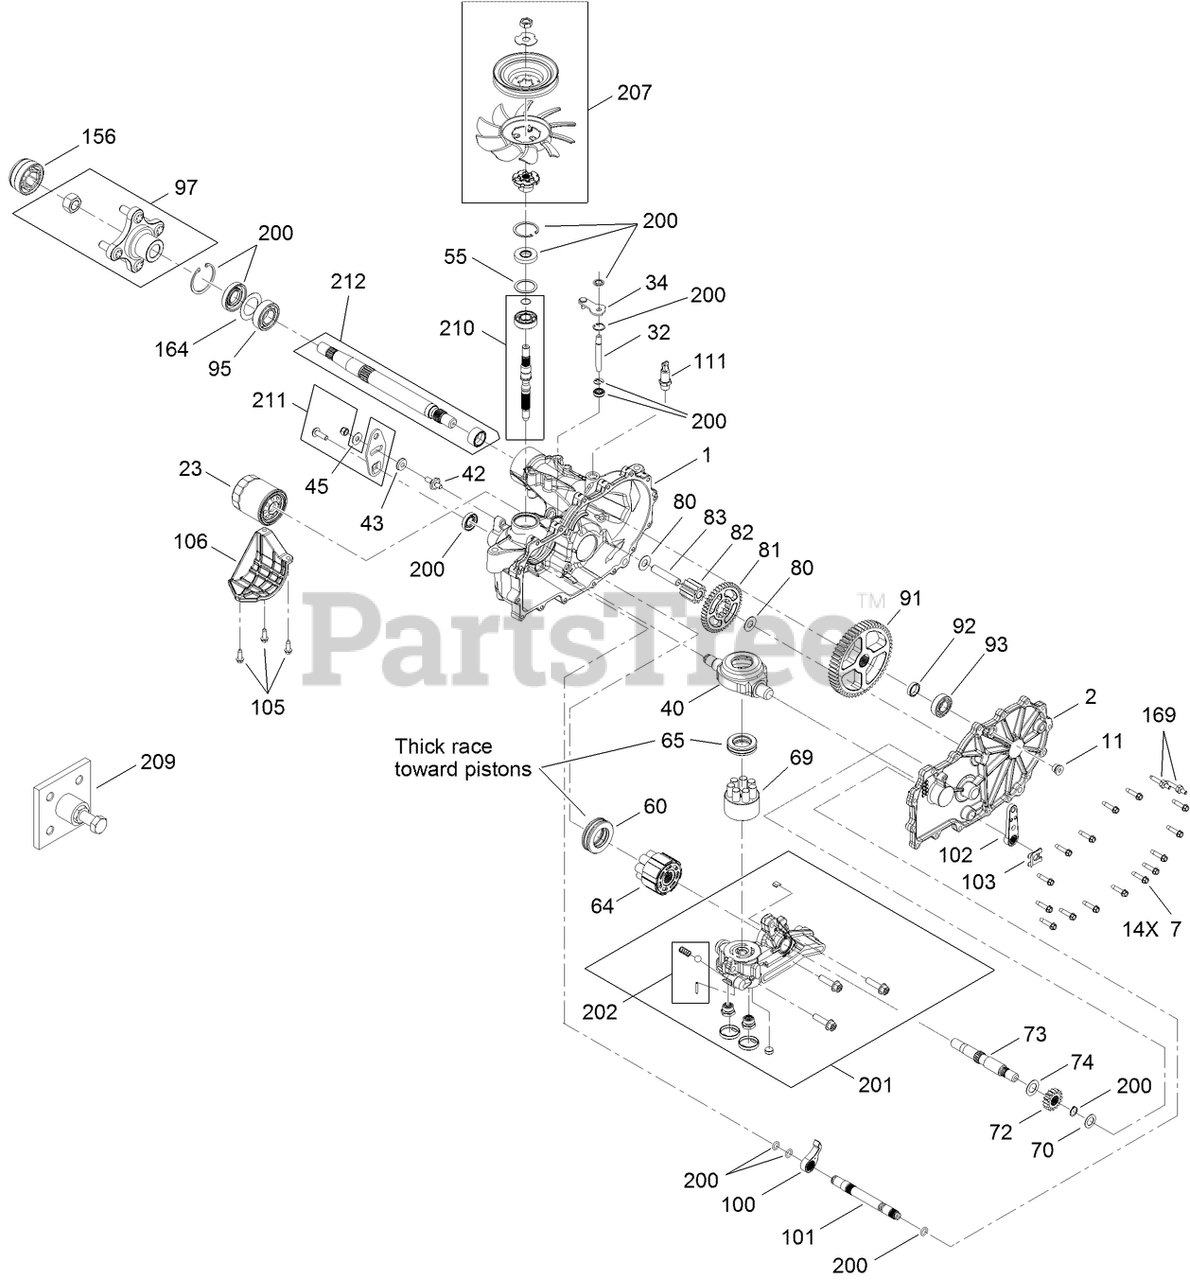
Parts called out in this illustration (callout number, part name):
1	MAIN HOUSING KIT
2	RH HOUSING SIDE KIT
7	SCREW-HHF
11	PLUG-THREAD, STRAIGHT
23	ELEMENT-OIL FILTER, HYD
32	ROD-BYPASS
40	SWASHPLATE-TRUNNION
43	PUCK-FRICTION
45	WASHER
55	SPACER
60	BEARING-THRUST
64	MOTOR CYLINDER BLOCK KIT
65	BEARING-THRUST
69	PUMP BLOCK ASM
70	WASHER-FLAT
72	GEAR-16T
73	SHAFT-MOTOR
74	WASHER
80	WASHER
81	GEAR-43T
82	GEAR-11T
83	PIN-JACKSHAFT
91	GEAR-54T
92	SPACER
93	BEARING-BALL
95	BEARING-BALL
97	HUB KIT
100	PAWL-BRAKE
101	SHAFT-BRAKE, INBOARD
102	HANDLE-BRAKE
103	CLIP-RETAINING
106	GUARD-FILTER, RH
111	ADAPTER-STRAIGHT
156	COVER-NUT, AXLE
164	SPACER
200	SEAL KIT
201	RH CENTER SECTION KIT
202	CHARGE RELIEF KIT
207	FAN PULLEY KIT
210	INPUT SHAFT KIT
211	CONTROL ARM KIT
212	AXLE SHAFT KIT
